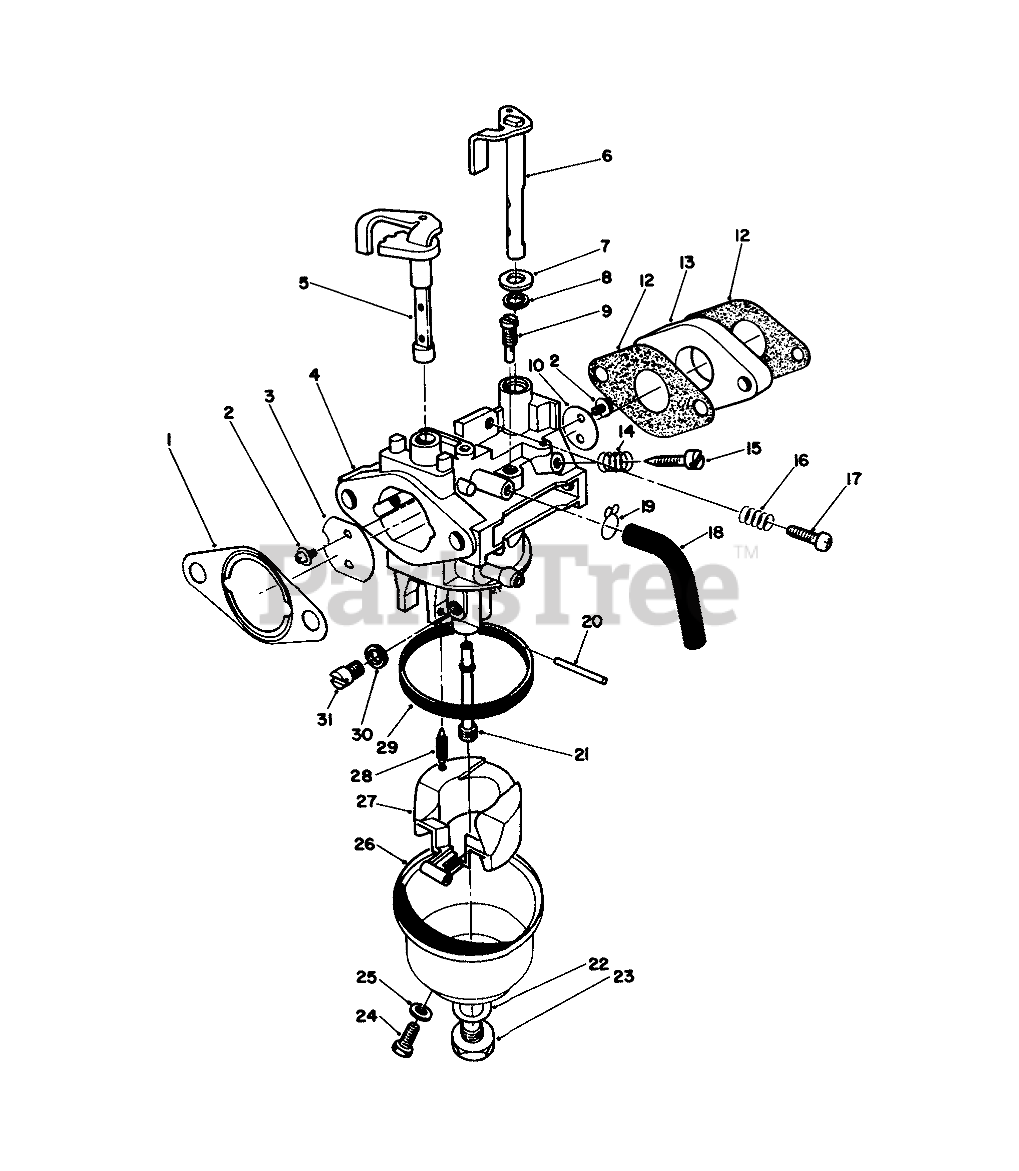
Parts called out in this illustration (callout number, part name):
1	GASKET F/W ENGINE
2	Screw
3	VALVE
4	Carburetor Assembly (Incl. Ref. #2-31)
5	SHAFT
6	SHAFT
7	WASHER
8	Seal-Throttle Shaft
9	PILOT JET
10	VALVE
12	Gasket-Carburetor
13	CARB INSULATOR
14	SPRING-PILOT SCREW
15	ADJUSTER
16	Spring-Idle Stop
17	SCREW
19	CLAMP
20	Pin
21	NOZZLE
22	GASKET
23	SCREW
24	SCREW
25	GASKET
27	Float
28	NEEDLE
29	FLOAT BOWL GASKET
30	SPACER
31	MAIN JET
